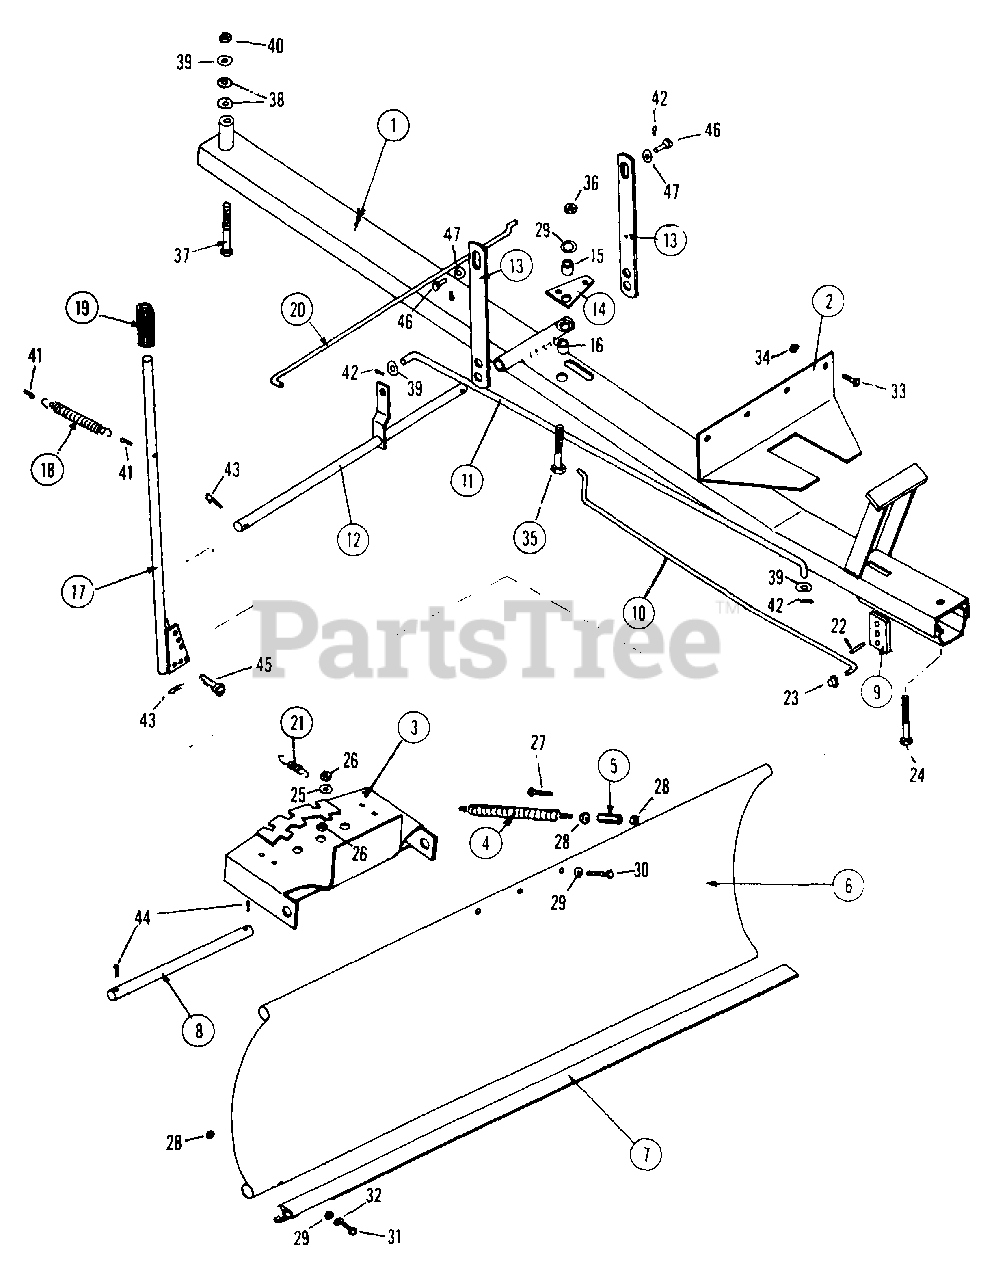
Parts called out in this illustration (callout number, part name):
1	FRAME, PUSH
2	GUIDE, PUSH FRAME
3	PLATE, PIVOT
4	SPRING, BLADE TRIP
5	NUT, COUPLER
6	BLADE, 42" DOZER
7	BAR, 42" BLADE WEAR
8	ROD, BLADE PIVOT
9	BAR, PIVOT LATCH
10	ROD, LATCH SIDE CONTROL
11	ROD, BLADE ANGLING
12	BAR, PIVOT
13	STRAP, BLADE LIFT
14	BELLCRANK, LATCH CONTROL
15	BUSHING, BELLCRANK
16	SPACER, BELLCRANK
17	HANDLE, BLADE ANGLING
18	SPRING, HANDLE RETURN
19	GRIP, HANDLE
20	ROD, LATCH CONTROL (LONG)
21	SPRING, LATCH BAR LOCK
22	PIN, SPIROL 1/4 x 1
23	NUT, 3/4C HALF HEX
24	BOLT, 3/4C x 4 HEX HEAD
25	WASHER, 3/4 ID. x 1-1/8 OD. FLAT
26	NUT, 3/4C HALF HEX
27	BOLT, 3/8C x 1 HEX FULL THREAD
28	NUT, 3/8C HEX
29	WASHER, 3/8" Flat
30	BOLT, 3/8C x 5-1/2 HEX HEAD
31	BOLT, 3/8C x 1 CARRIAGE
32	LOCKWASHER, 3/8
33	BOLT, 1/2C x 1 HEX HEAD
34	LOCKNUT, 1/2C HEX
35	BOLT, 3/8C x 1-1/2 HEX HEAD
36	LOCKNUT, 3/8C HEX
37	BOLT, 5/8C x 4-1/2 HEX HEAD
38	WASHER, 5/8ID x 1-3/8 OD. RUBBER
39	WASHER, 5/8 FLAT
40	LOCKNUT, 5/8C HEX
41	PIN, 3/16 x 1-1/2 COTTER
42	PIN, HAIR COTTER
43	PIN, HAIR COTTER
44	PIN, 5/32 x 1-1/4 COTTER
45	PIN, 3/8 x 1-1/4
46	PIN, 1/2 x 1 CLEVIS
47	WASHER, 1/2" FLAT
